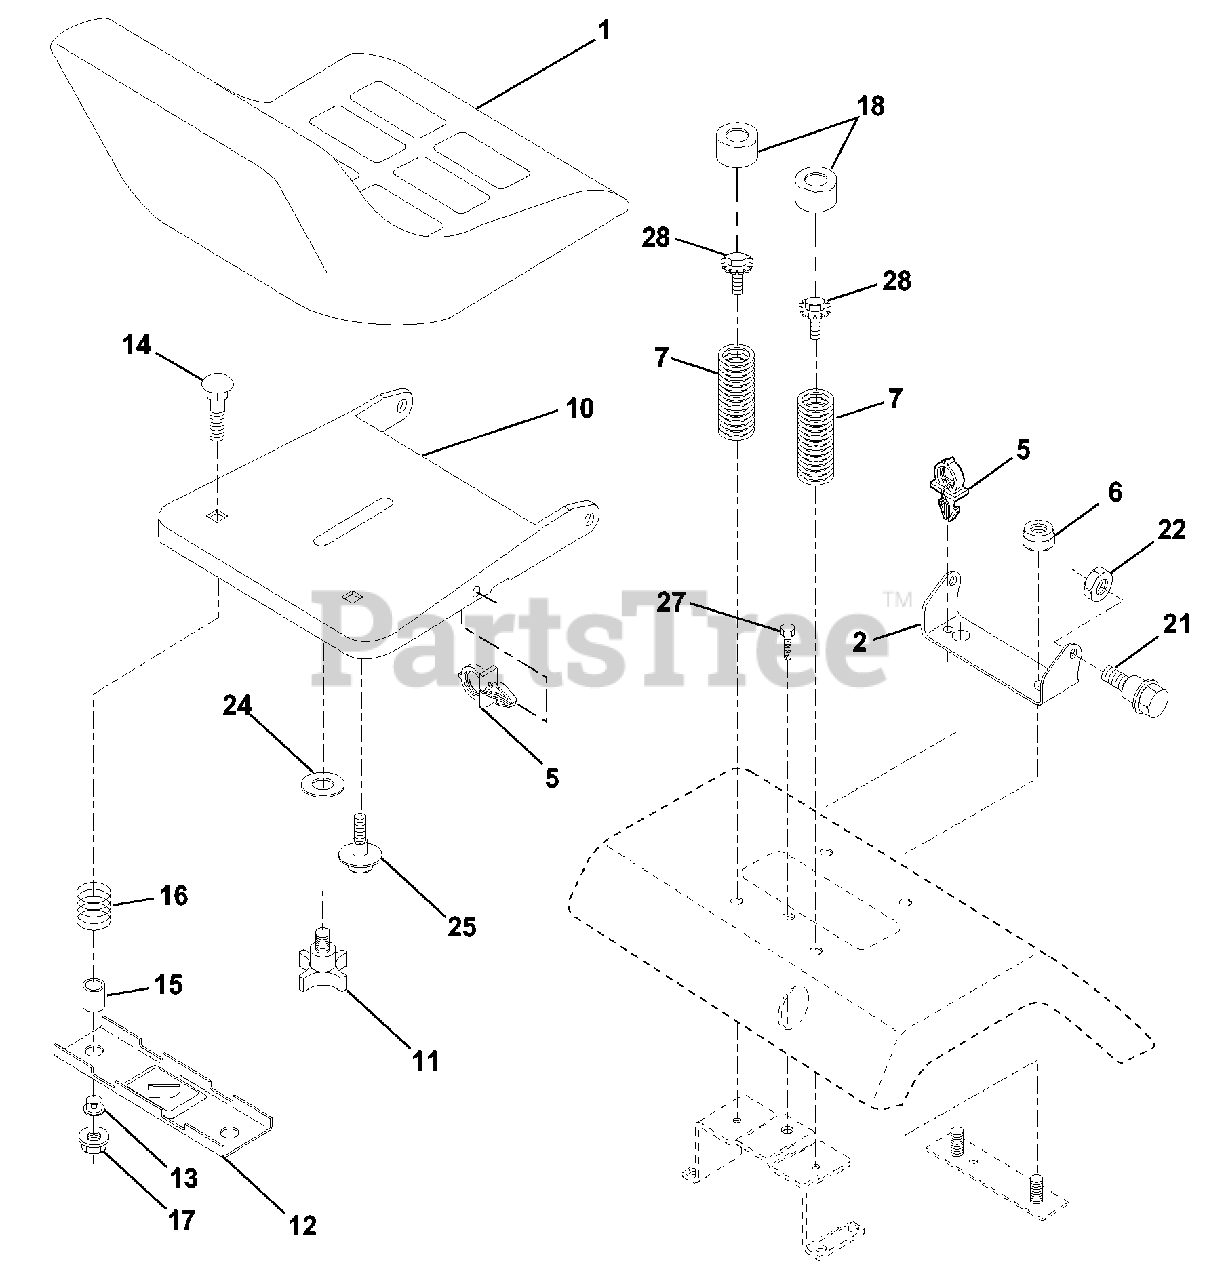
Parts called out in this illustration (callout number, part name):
1	Seat
2	Bracket Pivot Seat 8 720
5	Clip Push-In
7	Spring Seat Cprsn 2 250 Blk Zi
8	Screw Thdrol 5/16-18 X 1/2 TYT
9	Washer 13/32 X 1 X 14 Ga.
10	Pan Seat
11	Knob seat 1/2-13 Unc
12	Bracket Mounting Switch
13	Bushing Snap Blk Nyl 50 Id
14	Bolt Rdhd Sht Nk 1/4-20x1-3/8
15	Spacer Split 28x 96 Yel Zinc
16	Spring Cprsn 1 27 Blk Pnt
17	Nut Lock 1/4 Lge Flg Gr 5 Zinc
18	Cap Spring Seat
21	Bolt Shoulder 5/16-18 Unc Blkz
22	Nut Hex Lock W/Ins 5/16-18
24	Washer 17/32 X 1-3/16 X 12 Ga.
25	Bolt Shoulder 5/16-18 X 62
27	Screw, Thdrol. 3/8-16 x 12 TY-TT
28	Nut, Lock Hex w/Ins. 3/8-15 UNC
